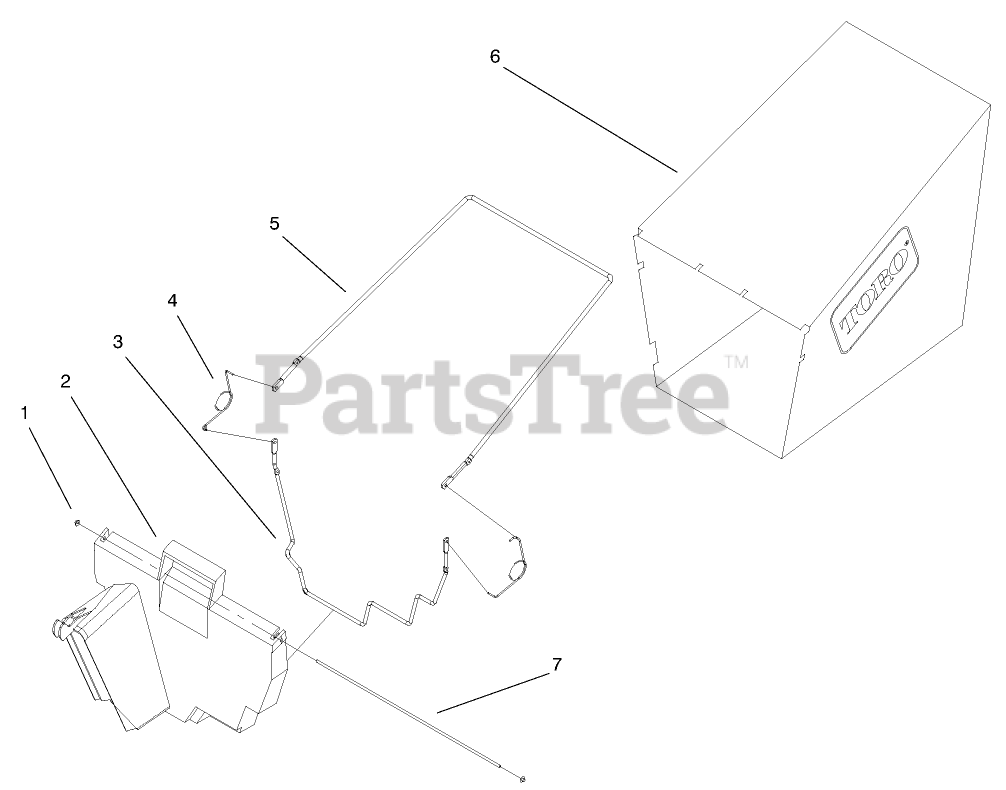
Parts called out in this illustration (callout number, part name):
1	NUT-PUSH
2	DOOR-BAG
3	FRAME-BAG, LOWER
4	SPRING
5	FRAME-BAG, UPPER
6	BAG-GRASS
7	HINGE-DOOR, BAG
